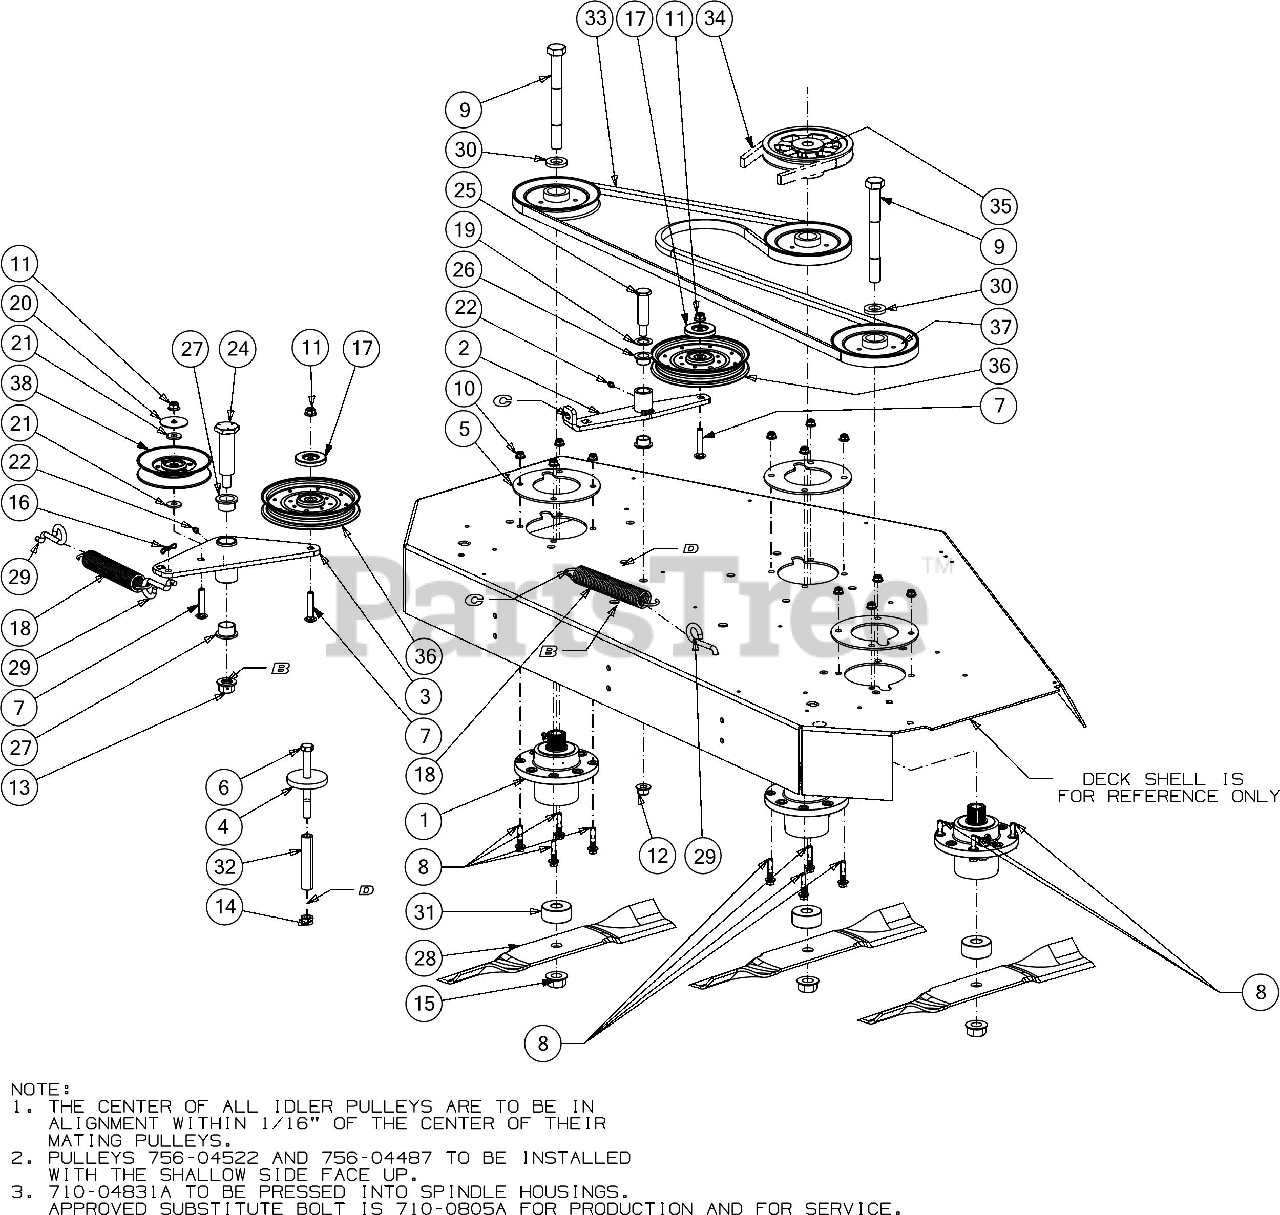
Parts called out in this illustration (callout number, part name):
1	SPINDLE ASSEMBLY
2	IDLER BRACKET
3	PTO IDLER ASSEMBLY
4	SPACER PLATE
5	SPINDLE TOP SUPPORT PLATE
6	BOLT-HEX 1/2-13X5.0 GR5
7	CARRIAGE BOLT 3/8-16 x 2
8	BOLT 5/16-18 x 1.50 GR5
9	SCREW 3/4-16 x 7.00 GR5
10	FLANGE LOCK NUT 5/16-18
14	HEX NUT CTR LK 1/2-13
15	HEX FLANGE NUT 3/4
16	BOW TIE COTTER PIN 1/4-5/16
17	PULLEY CAP
18	EXTENSION SPRING
19	FLAT WASHER .793ID x 1.24OD x .060
20	HUB CAP WASHER .406 x 1.92 x .060
21	FLAT WASHER .406ID X1.0 OD
22	GREASE FITTING
24	SHOULDER SCREW 1.0 x 3.15
25	SHOULDER SCREW
26	FLANGE BEARING
28	19" BLADE (HI LIFT)
30	SPACER .812 ID x .218 LG
33	BELT-B SECTION x 119.45
34	BELT-B SECTION x 99.1
35	PULLEY-6.96 OD x .750 ID
36	IDLER PULLEY
37	SPINDLE PULLEY 6"
38	IDLER PULLEY 5.06 OD
